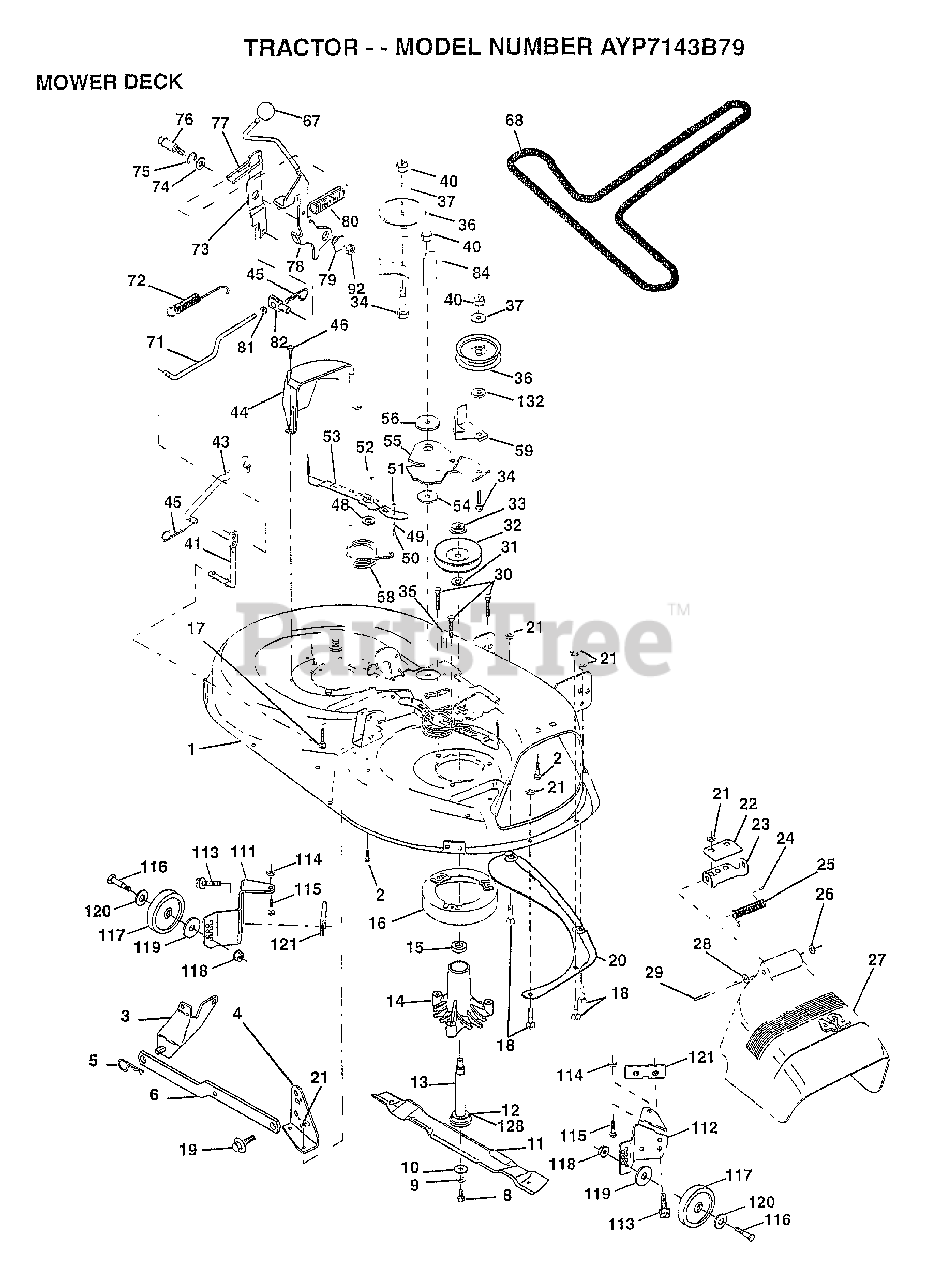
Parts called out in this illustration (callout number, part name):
1	DECK.WELD.42.
2	BOLT
3	BRKT ASM SWAY BAR
4	BRKT DECK SW BAR
8	BLADE BOLT
10	WASHER.HARD.BLADE
11	"BLADE.42"" MULCHER"
12	BEARING.BALL
14	HSG ASM MANDREL
15	BEARING
16	STRIPPER RND MWR
17	BOLT RDHD 3/8-16
18	BOLT
19	BOLT SHD 5/16-18
22	STIFFENER BRKT
23	DEFLECTOR BRKT
24	CAP-SLEEVE LT
25	SPRING TORSION
26	NUT PUSH M
27	DEFLECTOR.SHIELD
28	WASHER
29	HINGE ROD
31	WASHER
32	PULLEY.MANDREL.42
34	BOLT
35	XMAS TREE FASTNER
36	FLAT IDLER PULLEY
37	WASHER
41	PIVOT ROD
43	ROD CLUTCH W/NIBS
44	GUARD MAND LH BLK
45	RETAINER M
46	SCREW.1/4-20X5/8
48	HARD SMALL WASHER
49	ROLLER ASM-CAM
50	SHOULDER BOLT
51	LOCKNUT
52	BOLT.SHLD.5/16-18
54	HARDENED WASHER
55	ARM-IDLER
56	SPACER RETAINER
58	DECAL.SHIELD.TINE
59	GUARD IDLER TUV
67	KNOB T(3/8 HOLE)
68	BELT-V.SEC.46.KEL
71	ROD CLUTCH 38/42
72	RETURN SPRING
73	CLUTCH ARM SECOND
74	WASHER
75	RING
76	SHOULDER BOLT
77	SPRING KEEPER
78	LEVER ASM-CLUTCH
79	BUSHING
80	SPRING.CLUTCH.MWR
81	NUT
82	TRUNION ADJ
84	BRACKET ASM IDLER
92	NUT
111	BRACKET.GWHL.LH.
112	BRACKET.GWHL.RH.
113	SCREW
116	BOLT M
117	WHEEL.GAGE.BLK.PL
118	LOCKNUT
119	WASHER
120	WASHER
121	BRACKET.EXTRD.GWL
128	WASHER.FELT.
132	WASHER GT
